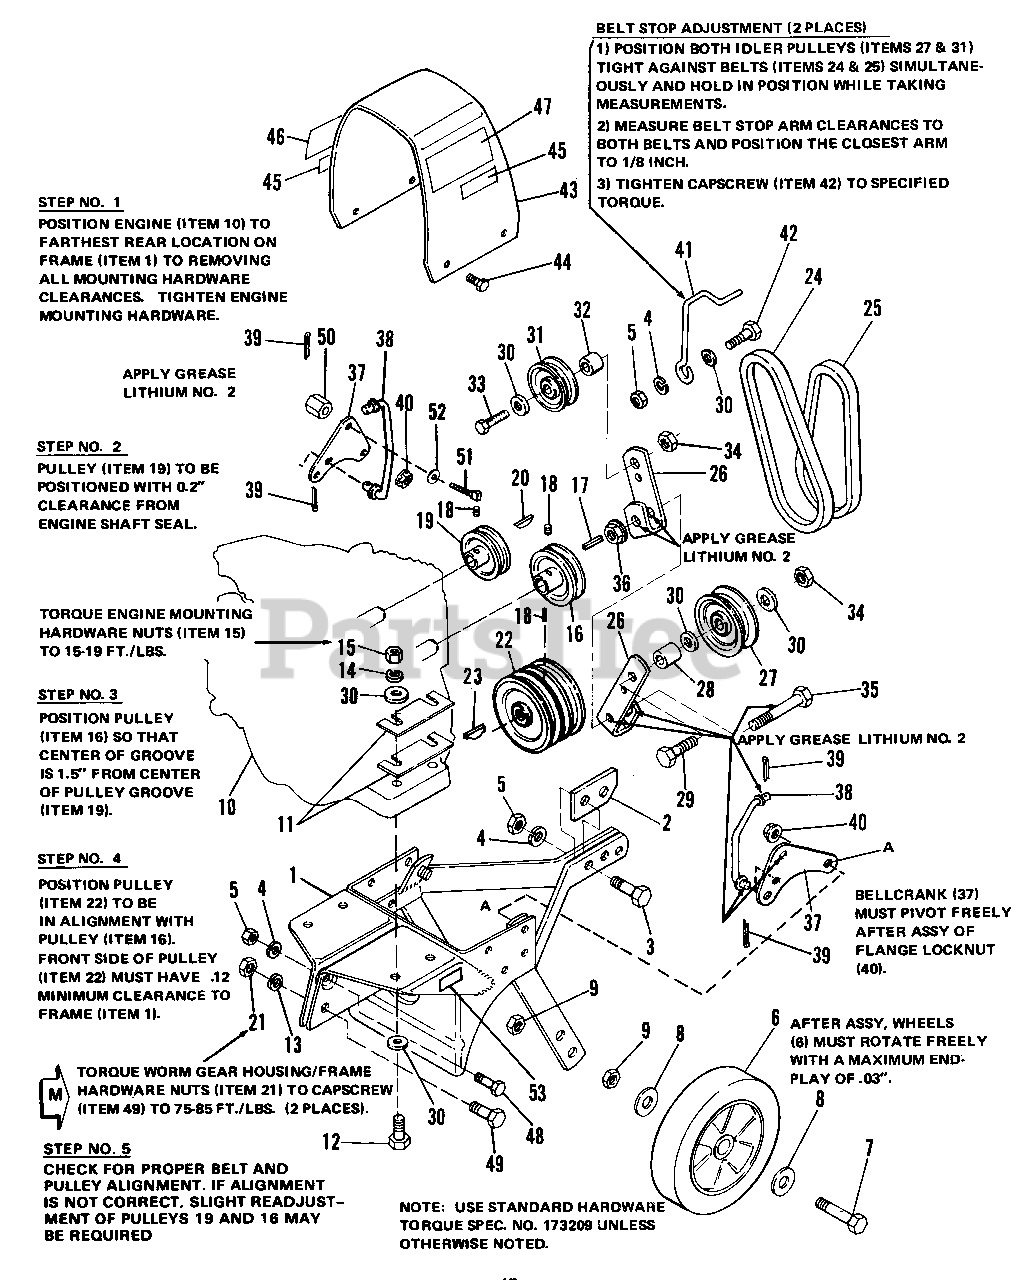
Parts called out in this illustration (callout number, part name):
1	FRAME ASSY
2	STOP, Plate
3	CAPSCREW, Hex, 3/8-16 x 1-1/2
4	LOCKWASHER, 3/8
5	NUT, Hex, Full, 3/8-16
6	WHEEL & TIRE ASSY
7	CAPSCREW, Hex, 1/2-13 x 3-1/2
8	WASHER, Plain, 1/2
9	NUT, Hex, Jam, 1/2-13
12	CAPSCREW, Hex, 5/16-18 x 2, Gr. 5
13	LOCKWASHER, 7/16
14	LOCKWASHER, 5/16
15	NUT, Hex, Full, 5/16-18
16	PULLEY, Engine (Forward)
18	SETSCREW, 5/16-18 x 5/16
19	PULLEY, Engine (Reverse)
20	KEY, 1/8 x 5/8, #5
21	NUT, Hex, Full, 7/16-20
22	PULLEY, Drive
24	BELT, (Reverse)
25	BELT (Forward)
26	LEVER, Idler Pulley
29	CAPSCREW, 3/8-16 x 1/2
30	WASHER, Plain, 5/16
31	PULLEY, Idler
33	CAPSCREW, Hex, 3/8-16 x 1-1/4
34	LOCKNUT, Hex, Full, 3/8-16
35	BOLT, Pivot
36	LOCKNUT, Flange, Whiz, 5/16-18
37	BELLCRANK
38	LINK, Rod
39	PIN, Cotter, 5/8 x 3/4
40	LOCKNUT, Hex, Flange, 5/16-18
41	STOP, Belt
42	CAPSCREW, Hex, 3/8-16 x 1
43	COVER, Engine
44	SCREW, Taptite, 1/4-20 x 3/8
45	DECAL, 1004
46	DECAL, Roticul, R.H.
47	DECAL, Roticul, L.H.
48	CAPSCREW, Hex, 3/8-16 x 3/4
49	CAPSCREW, Hex, 7/16-20 x 1-1/4
50	CLAMP, Wire
51	SETSCREW, #10-24 x 5/8
52	WASHER, Plain, 3/16
53	I.D. PLATE
